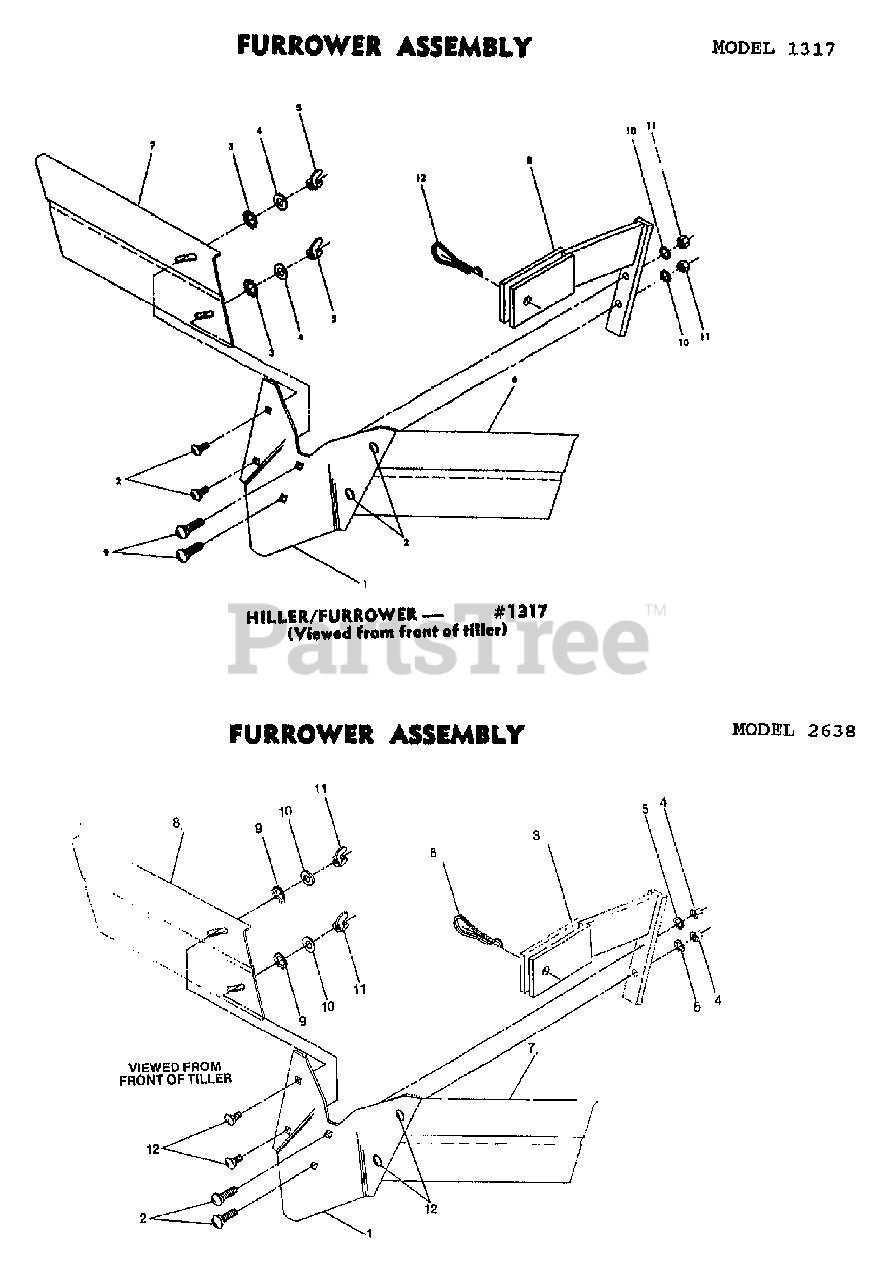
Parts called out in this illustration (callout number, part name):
1	BLADE-FURROWER PNT
2	BOLT-CARR 3/8-16X1.5 ZP
3	BRKT-H/F PNT
4	NUT-HEX 3/8-16 ZP
5	WASHER-LK .375 @ DEPL
6	PIN-CLINCH .312DIA ZP
7	WING-HILLER LEFT PNT
8	WING-HILLER RIGHT PNT
9	WASHER-LK .312 EXT TOOTH
10	WASHER-FLAT 5/16 SAE
11	NUT-WING/LK 5/16-18 ZP
12	SCR-CARR 5/16-18X.75 G2 ZP
